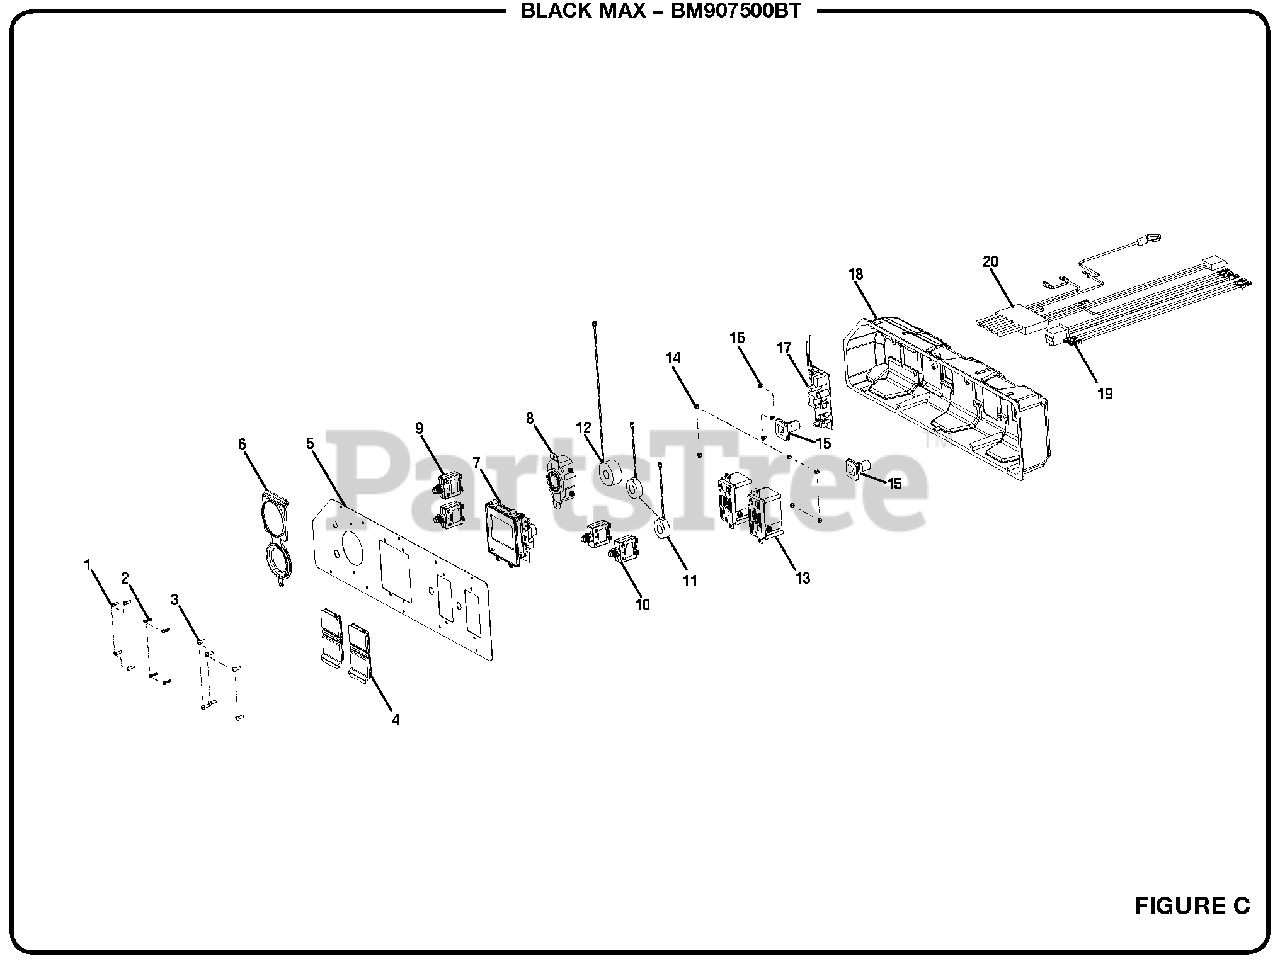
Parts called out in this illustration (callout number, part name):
1	Screw (6-20 x 3/8 in., Pan Hd.)
2	Screw (M3.1 x 10 mm, Pan Hd.)
3	Screw (M4 x 10 mm, T10 Torx Pan Hd.)
4	120V Duplex Receptacle Cover
5	Control Panel Faceplate
6	Twist Lock Receptacle Cover
7	Display Assembly
8	120/240V Receptacle (30A)
9	Circuit Breaker (30A)
10	Circuit Breaker (20A)
11	Circuit Current Transformer Type A- 20V
12	Circuit Current Transformer Type B- 240V
13	120V GFCI Duplex Receptacle
14	Lock Nut (6-32, Hex Hd.)
15	Wire Protector
16	Screw (M3 x 5 mm, T10 Torx Pan Hd.)
17	Circuit Board Assembly
18	Control Box
19	Maxcontrol Wire Harness
20	Wire Harness
